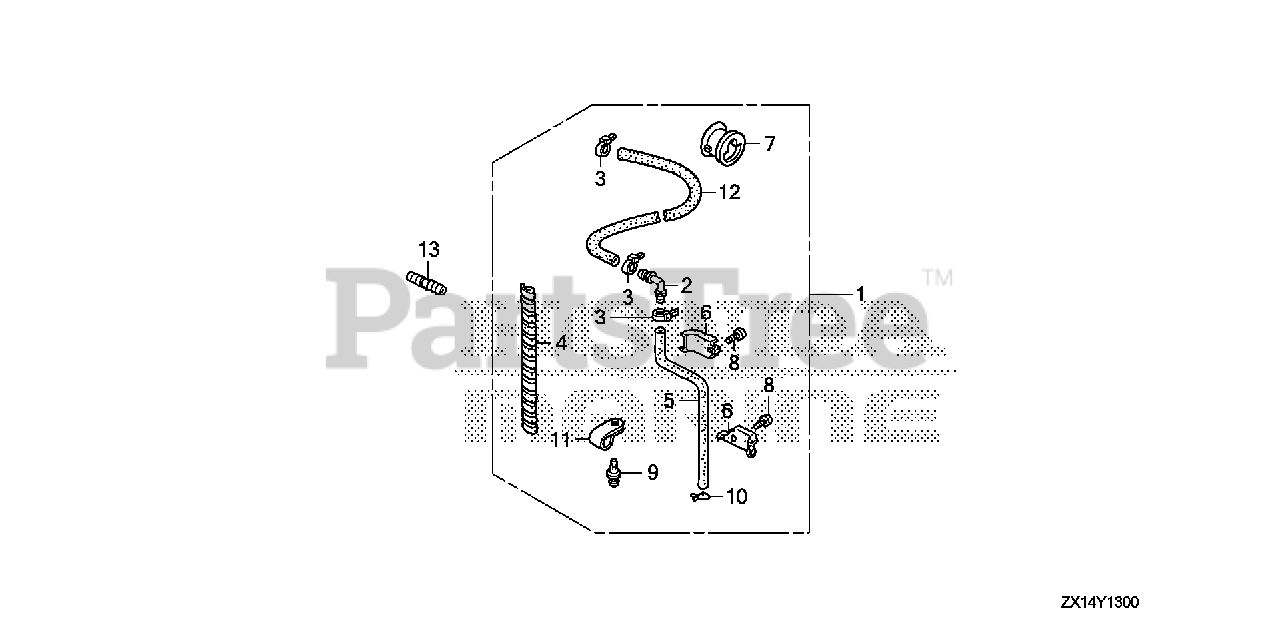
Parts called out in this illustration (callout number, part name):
1	TUBE KIT, SPEED SENSOR
2	JOINT A, BREATHER
3	BAND, WIRE
4	TUBE, SPIRAL
5	TUBE, SPEED SENSOR
6	PLATE, SPEED SENSOR TUBE
7	BUSH, MOTOR CODE
8	SCREW, PAN (6X8)
9	SCREW, RIVET (5X10)
10	CLIP, TUBE (B8)
11	CLIP (14MM)
12	BULK HOSE, VACUUM (5X3000) (5X250)
13	END, NIPPLE
